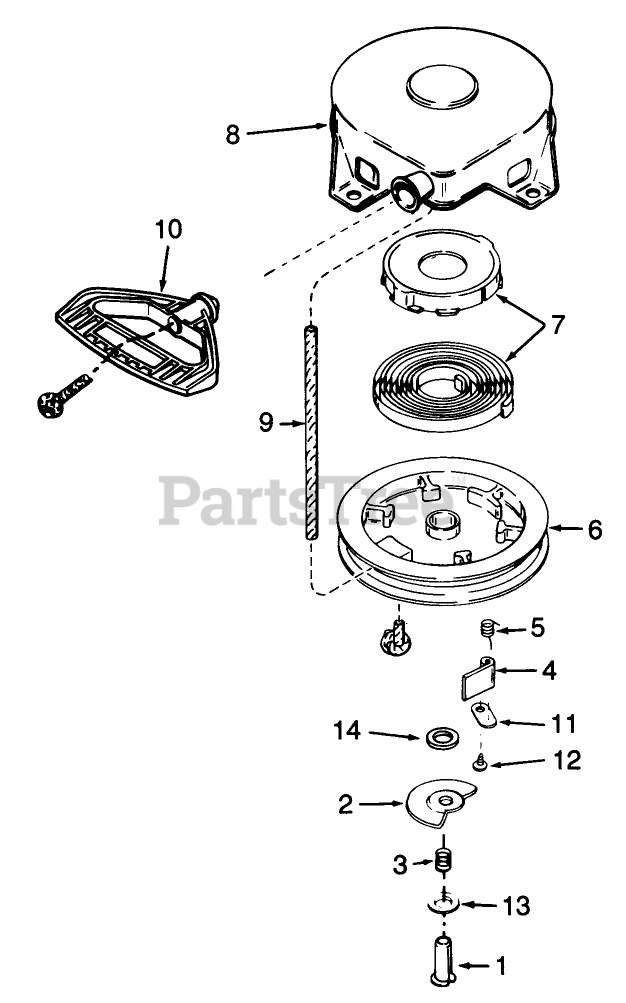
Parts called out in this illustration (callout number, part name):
1	Pin, Spring (Incl. Ref. #7)
2	Washer
3	Brake Spring
4	Dog-Starter
5	Spring-Dog
6	Pulley
7	Spring Keeper Assy
8	Housing-Starter
9	Rope-Starter
10	Handle-Starter, Mitten Grip
11	Retainer-Dog
12	Screw
13	Washer
14	Washer
